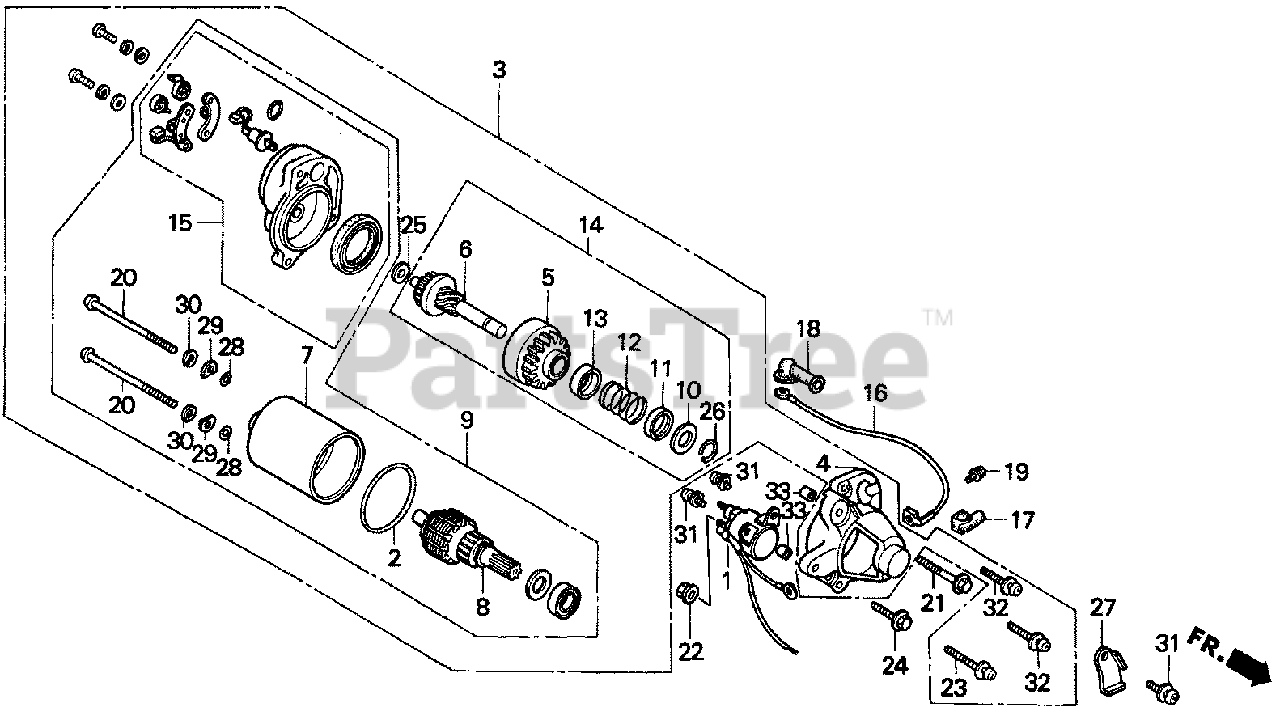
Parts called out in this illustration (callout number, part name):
1	SWITCH, MAGNETIC
2	O-RING
3	MOTOR UNIT, STARTER
4	COVER, GEAR
5	PINION ASSY.
6	SHAFT UNIT, GEAR
7	YOKE ASSY.
8	ROTOR ASSY.
9	MOTOR ONLY
10	PIECE A, STOPPER
11	PIECE B, STOPPER
12	SPRING, RETURN
13	COVER, SPRING
14	GEAR ASSY.
15	BRACKET, FR.
16	WIRE, MAGNET SWITCH
17	COVER, MAGNET SWITCH TERMINAL
18	COVER, STARTER MOTOR TERMINAL
19	SCREW-WASHER (5X8)
20	BOLT, SETTING
21	BOLT, FLANGE (6X32)
22	NUT-WASHER (6MM)
23	SCREW-WASHER (5X30)
24	BOLT, FLANGE (6X25)
25	WASHER, PINION (NOT AVAILABLE)
26	CIRCLIP (10.2MM)
27	HOLDER, HARNESS
28	O-RING
29	WASHER, SPECIAL
30	WASHER, SPRING
31	SCREW-WASHER (5X14)
32	SCREW-WASHER (5X20) (NOT AVAILABLE)
33	PIN A, DOWEL (8X10)
